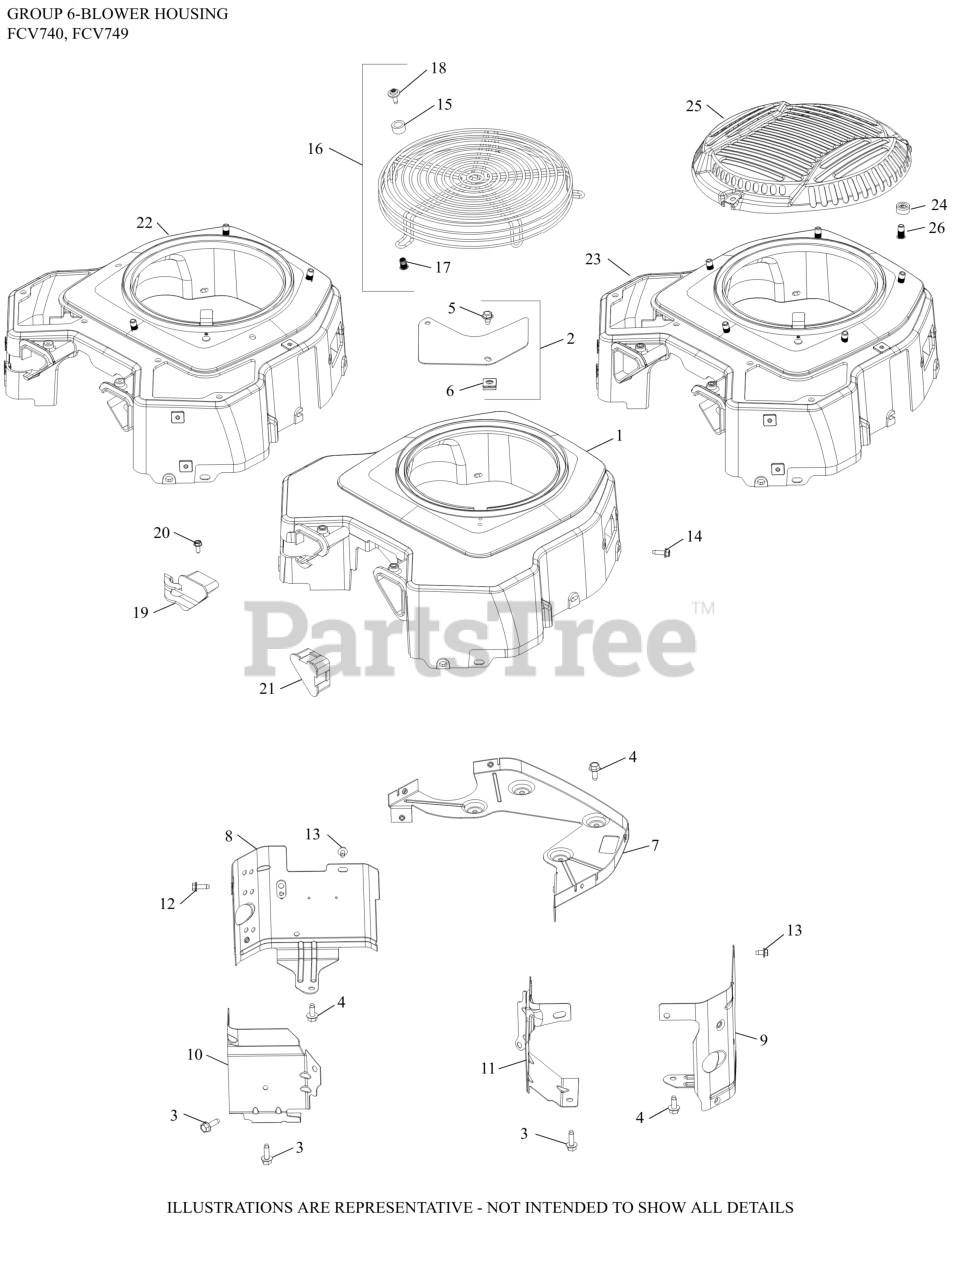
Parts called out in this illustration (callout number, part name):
2	KIT, ACCESS PANEL
3	SCREW, THREAD FORMING
4	SCREW, THREAD FORMING
5	SCREW, THREAD FORMING
6	CLIP, BAFFLE MOUNTING
7	PLATE, BACKING
7	KIT, BACKING PLATE
8	KIT, RIGHT BARREL
9	BAFFLE LEFT BARREL
11	BAFFLE, VALLEY #2 CYLINDER
12	SCREW, THREAD FORMING
13	SCREW, THREAD FORMING
14	SCREW, THREAD FORMING
16	KIT, GUARD
18	SCREW, SEMS
19	COVER, BLOWER HOUSING
21	COVER, BLOWER HOUSING
22	HOUSING, BLOWER
NI	BAFFLE, VALLEY #1 CYLINDER
NI	INSERT, THREADED (M5)
